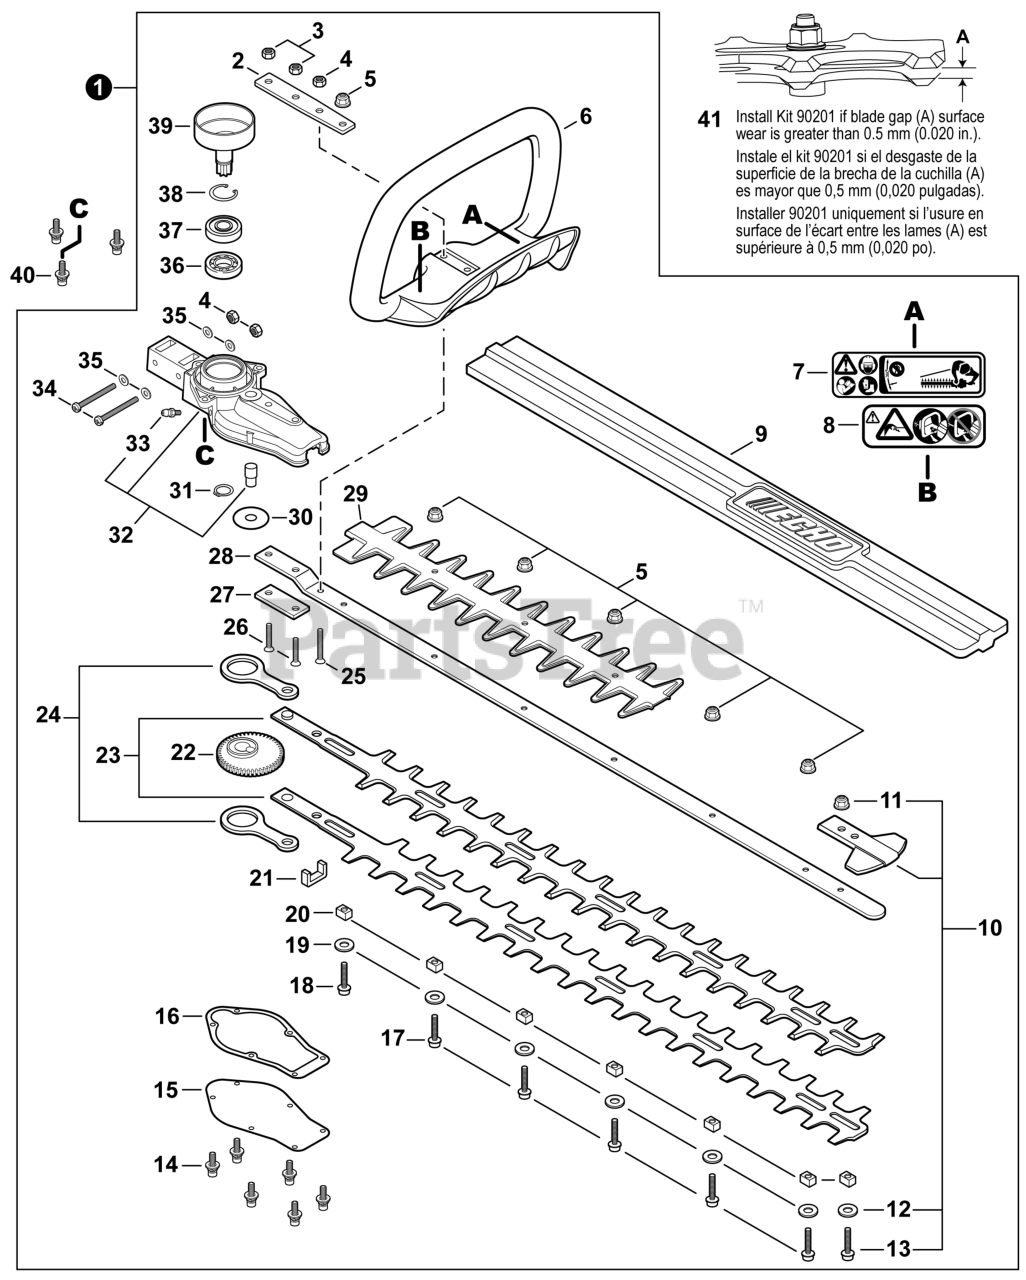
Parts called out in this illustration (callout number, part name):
1	CUTTING HEAD KIT
2	PLATE, SUPPORT
3	NUT, HEX M6
4	NUT, LOCK M5
5	NUT, FLANGE M5
6	HANDLE, FRONT
7	LABEL - CAUTION - ISO
8	LABEL - CAUTION
9	SCABBARD
10	TIP GUARD KIT
11	NUT, FLANGE M5
12	WASHER 5
13	BOLT 5x20
14	BOLT 4x10
15	COVER, GEAR CASE
16	GASKET, GEAR CASE
17	BOLT 5x20
18	BOLT 5x40
19	WASHER 5
20	GUIDE, BLADE 5
23	CUTTER 24"
24	ROD, CONNECTING
25	SCREW 5x30
26	SCREW 6x25
27	PLATE, EYE
28	SUPPORT, BLADE 24"
29	GUARD, CUTTER BLADE
31	RING, SNAP 14
32	GEAR CASE ASSY
33	FITTING, GREASE
34	SCREW 5x45
35	WASHER, FLAT 5.5x10x0.8
36	BEARING, BALL 6202
37	BEARING, BALL 6202
38	RING, SNAP 35
39	DRUM, CLUTCH
40	BOLT 5x20
41	BLADE KIT, ADJUSTABLE
